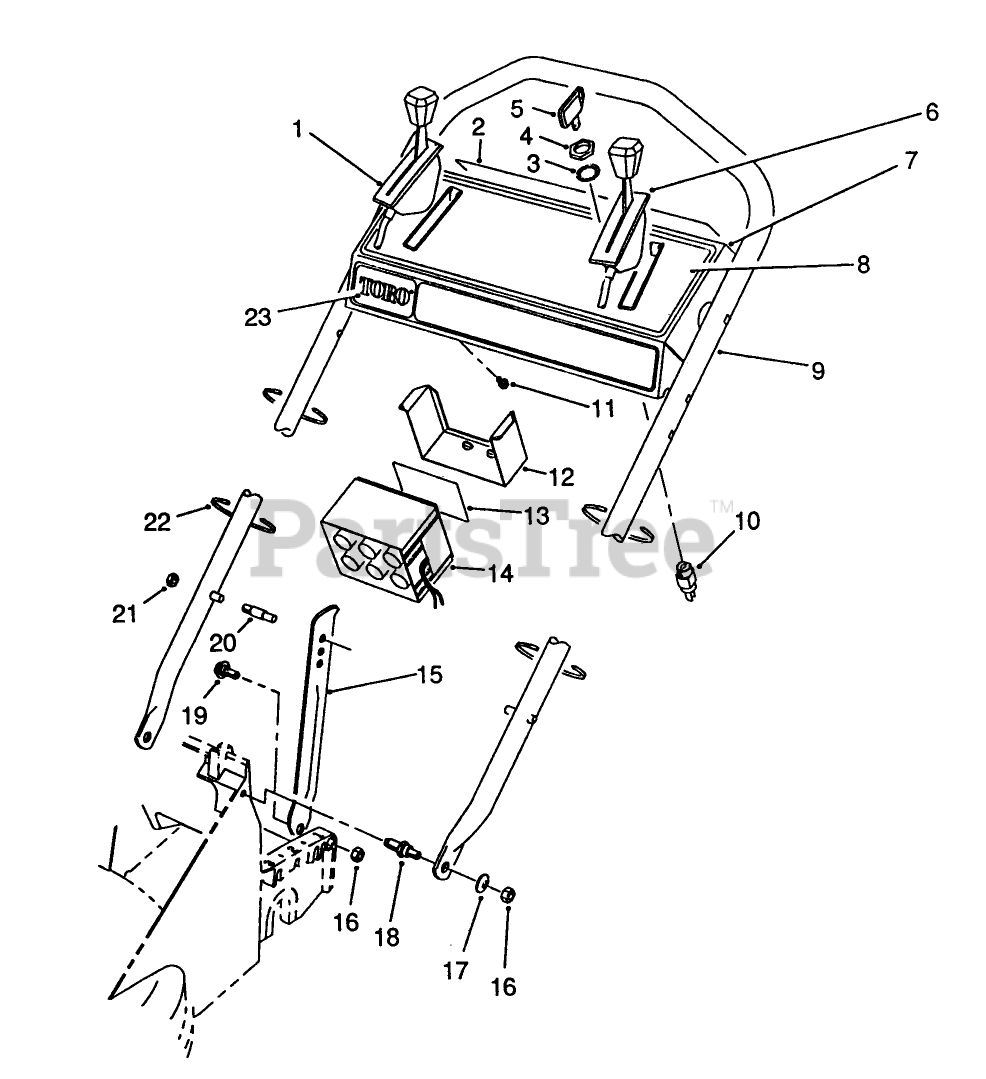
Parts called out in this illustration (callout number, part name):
2	DECAL-PANEL, DANGER
3	WASHER-LOCK
4	NUT-HH
5	KEY-IGNITION
7	PANEL W/ DECAL ASM
10	STARTER SWITCH ASM
11	SCREW-HWHTF
14	BATTERY ASSEMBLY,WET
16	NUT-LOCK, NI
17	WASHER-PLAIN
20	HANDLE PIN
21	NUT-LOCK, NI
22	TIE-CABLE
